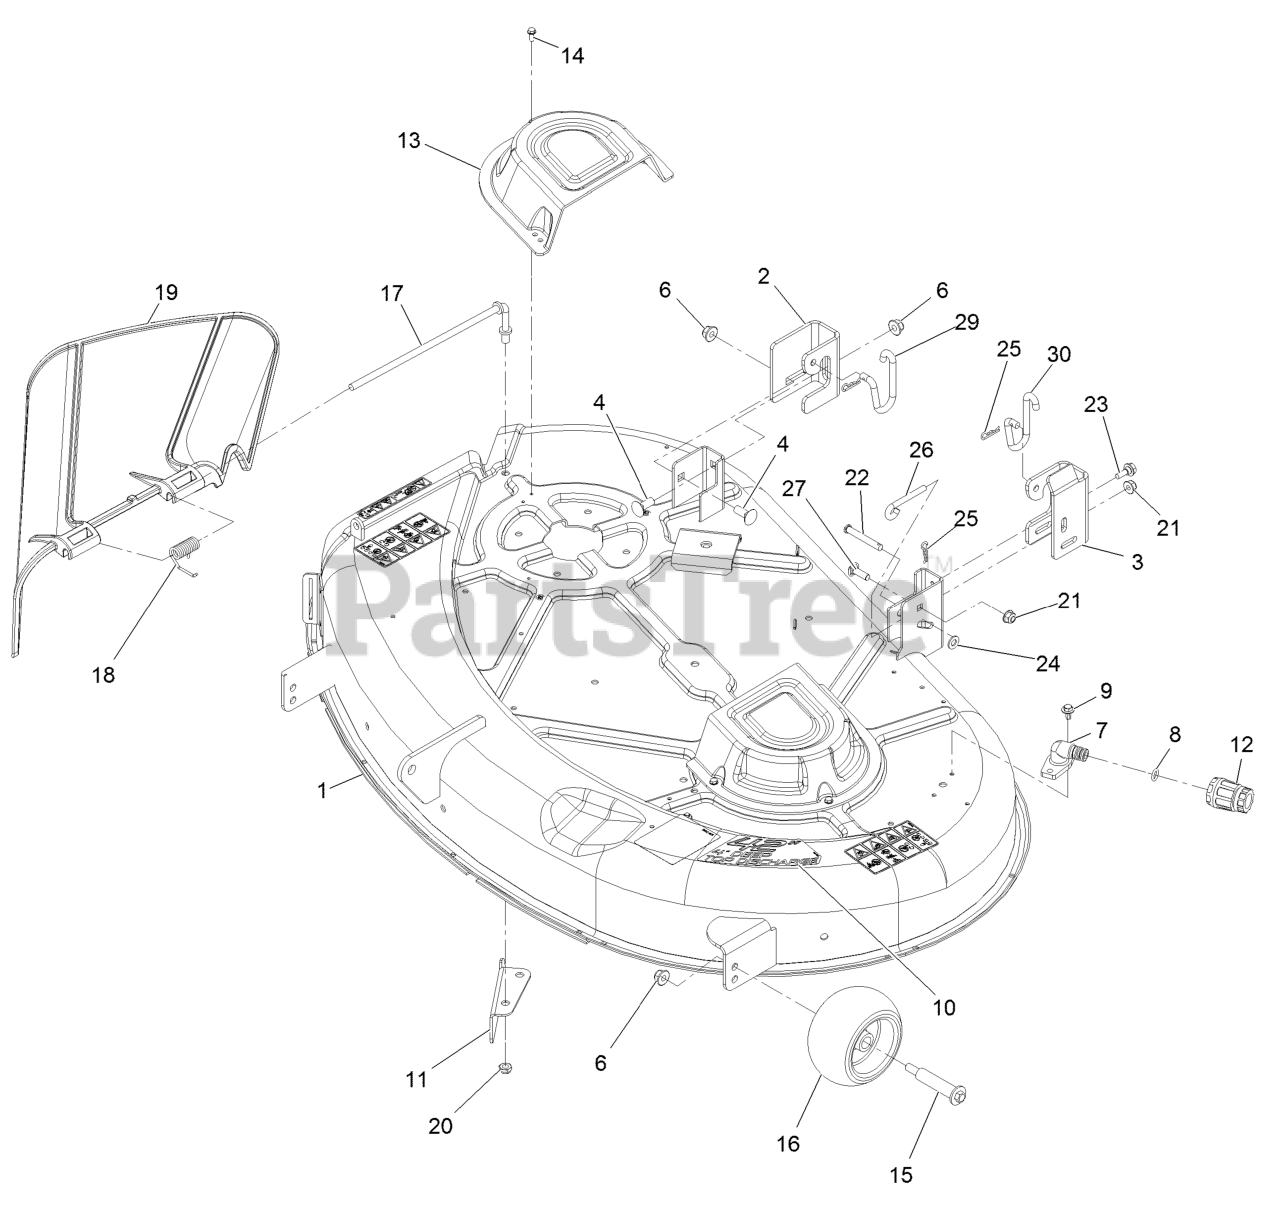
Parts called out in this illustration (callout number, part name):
1	42 INCH DECK AND DECAL AS
2	BRACKET-HANGER, RH
3	BRACKET-HANGER, LH
4	BOLT-CARR
6	NUT-HF, NI
9	SCREW-HHFTF
11	BAFFLE-CUTOFF
12	CONNECTOR-HOSE
13	COVER-BELT
14	SCREW-TAPTITE
15	BOLT-SHOULDER
16	ROLLER-SCALP, ANTI
17	ROD-PIVOT
18	SPRING-TORSION
19	DEFLECTOR
21	NUT-HF, NI
22	PIN-CLEVIS
23	SCREW-SHOULDER,HWH
24	WASHER-PLAIN
25	PIN-COTTER
26	ROD-LEVEL, DECK
27	SCREW-CARR
29	LINK-RETENTION, DECK (RH)
30	LINK-RETENTION, DECK (LH)
